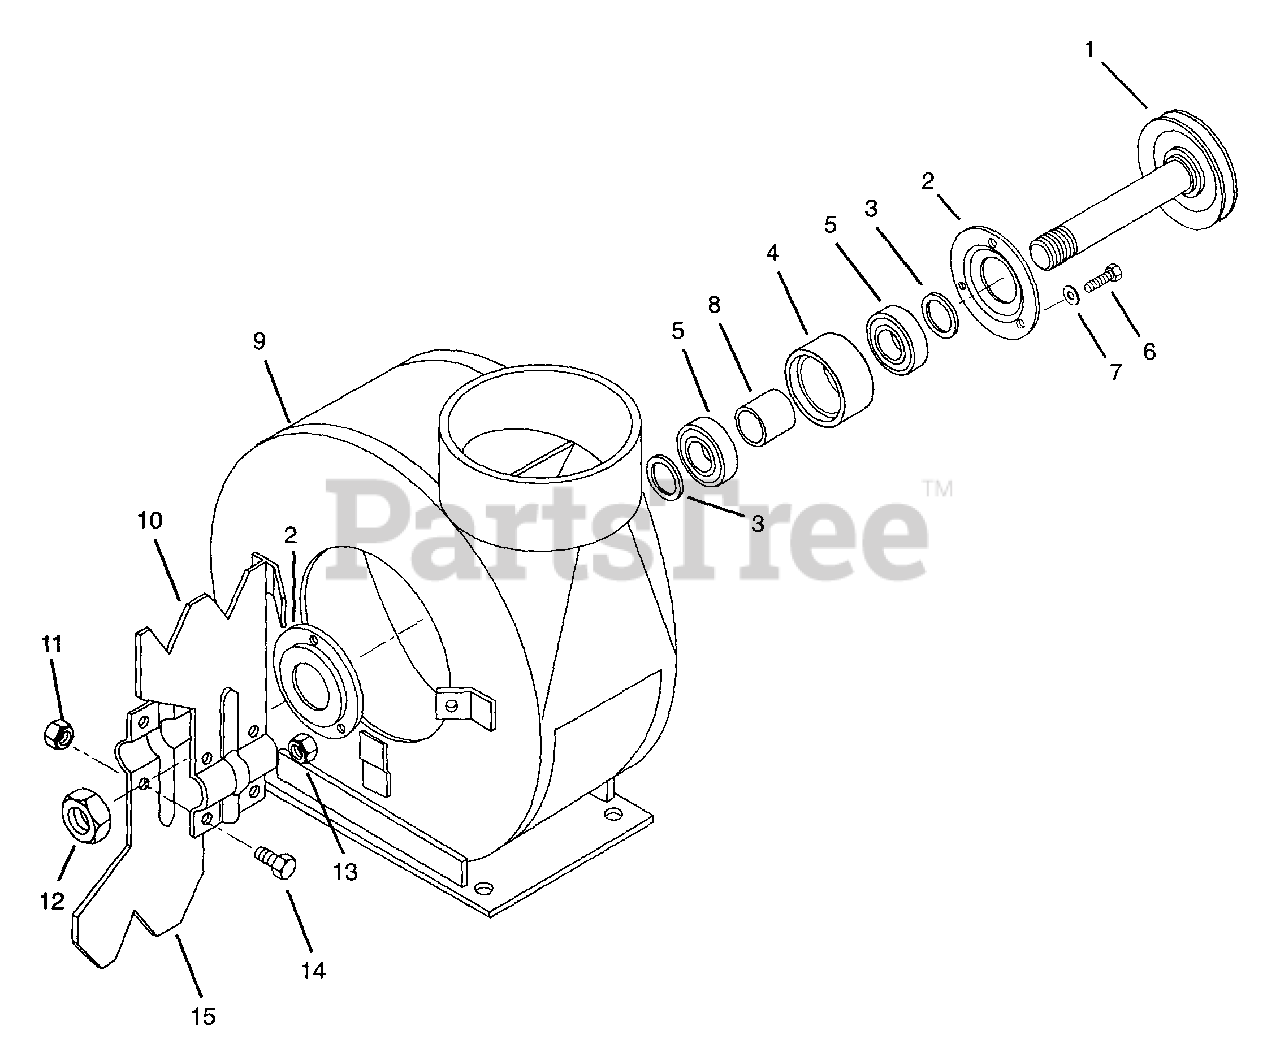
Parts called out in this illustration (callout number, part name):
1	Weldment, Spindle
2	Bearing, Flange
3	Washer-Flat-Steel 1.015 x 1.500 x .125
5	Bearing, Ball 1.00 x 2.00
6	Bolt-Hex .25-20 x 2.00 Grade 5
7	Washer-Flat .263 x .562 x .040
9	Housing, Blower
10	Fan Blade
11	Nut-Locking .31-18
12	Nut-Locking-Jam 1.00-14
13	Nut-Locking-Center .25-20
14	Bolt-Hex .31-18 x .625 Grade 5
15	Fan Blade
